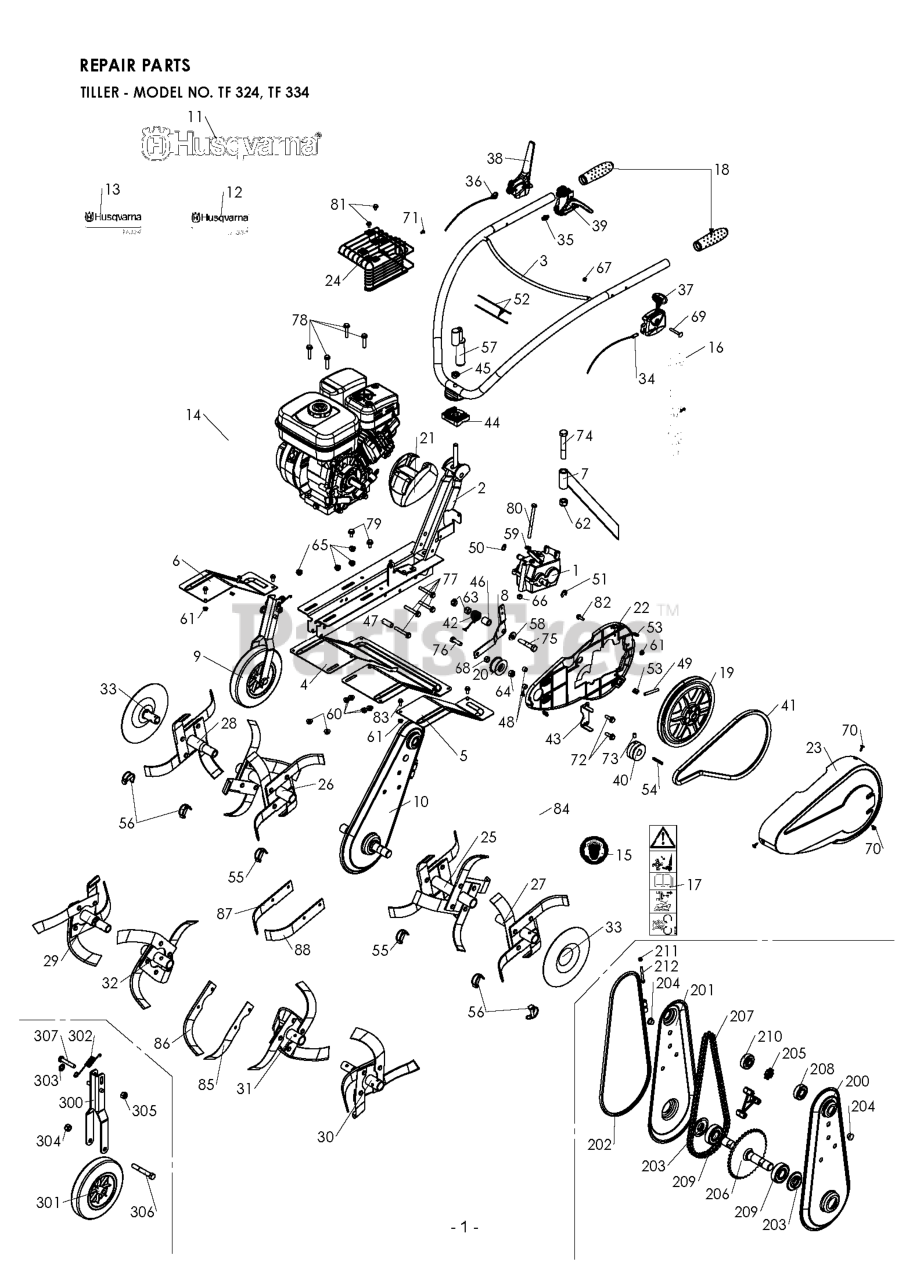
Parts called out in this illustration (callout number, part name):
8	ARM
51	RETAINER RING
67	Blocking nut M 6 Z
211	Blocking nut M 6 Z
